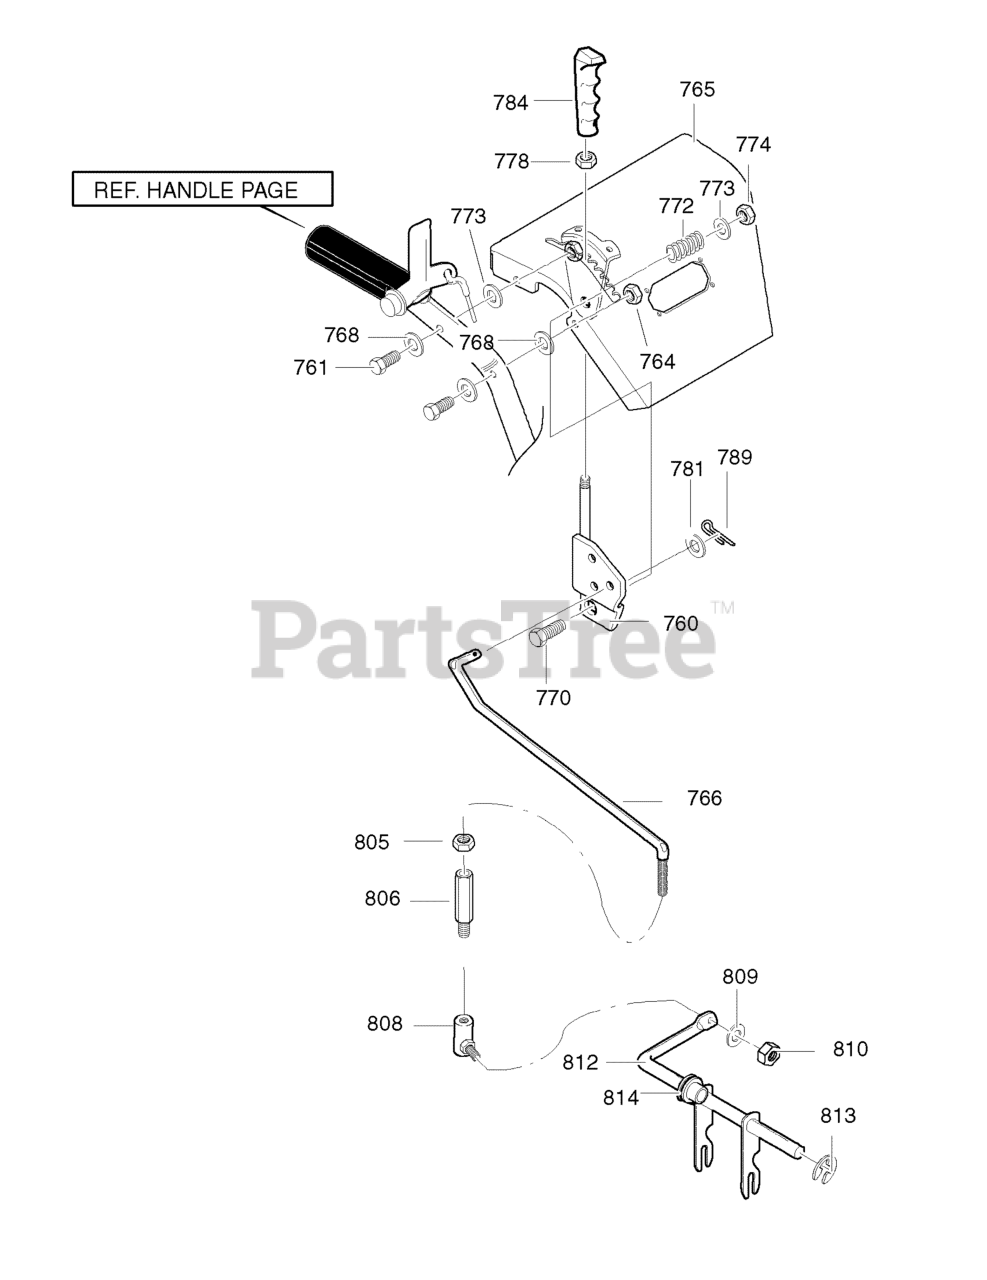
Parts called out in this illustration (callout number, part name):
760	HANDLE ASSEMBLY SPEED CONTROL
761	SCREW, 5/16-18 x 1.75
764	NUT, 5/16-18
765	ASSEMBLY BAY PANEL - LT
766	ROD, SPEED CONTROL
768	WASHER
770	SCREW 3/8-16 X 2.00
773	WASHER, Flat, 13/32
774	NUT, 3/8-16
778	NUT, 3/8-16
781	FLATWASHER
784	HANDLE, GRIP
789	PIN, COTTER
805	NUT, 5/16-18
806	ADAPTER, SPEED ROD -YZ
808	BALLJOINT, STEEL -YZ
809	WASHER
810	NUT, 5/16-18
812	ROD, ASSEMBLY YOKE
813	RING, RETAINER
814	BEARING, FLANGE
